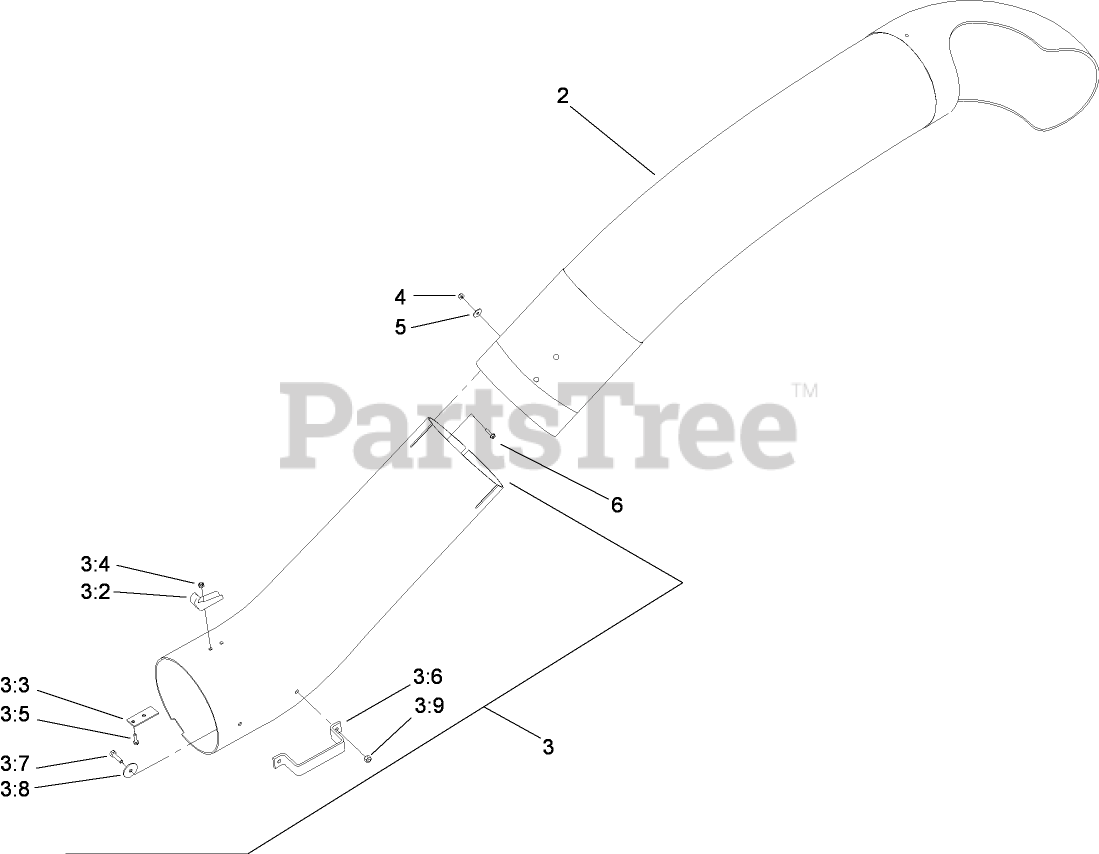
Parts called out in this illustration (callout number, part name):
2	TUBE-UPPER
3	LOWER TUBE ASM
3:2	LATCH-CATCH
3:3	PLATE-BACKING
3:4	NUT-LOCK, NI
3:5	SCREW-HWH
3:7	SCREW-HH
3:8	WASHER-FLAT
3:9	NUT-LOCK, NI
4	NUT-LOCK, NI
5	WASHER-FLAT
6	SCREW-HWH
